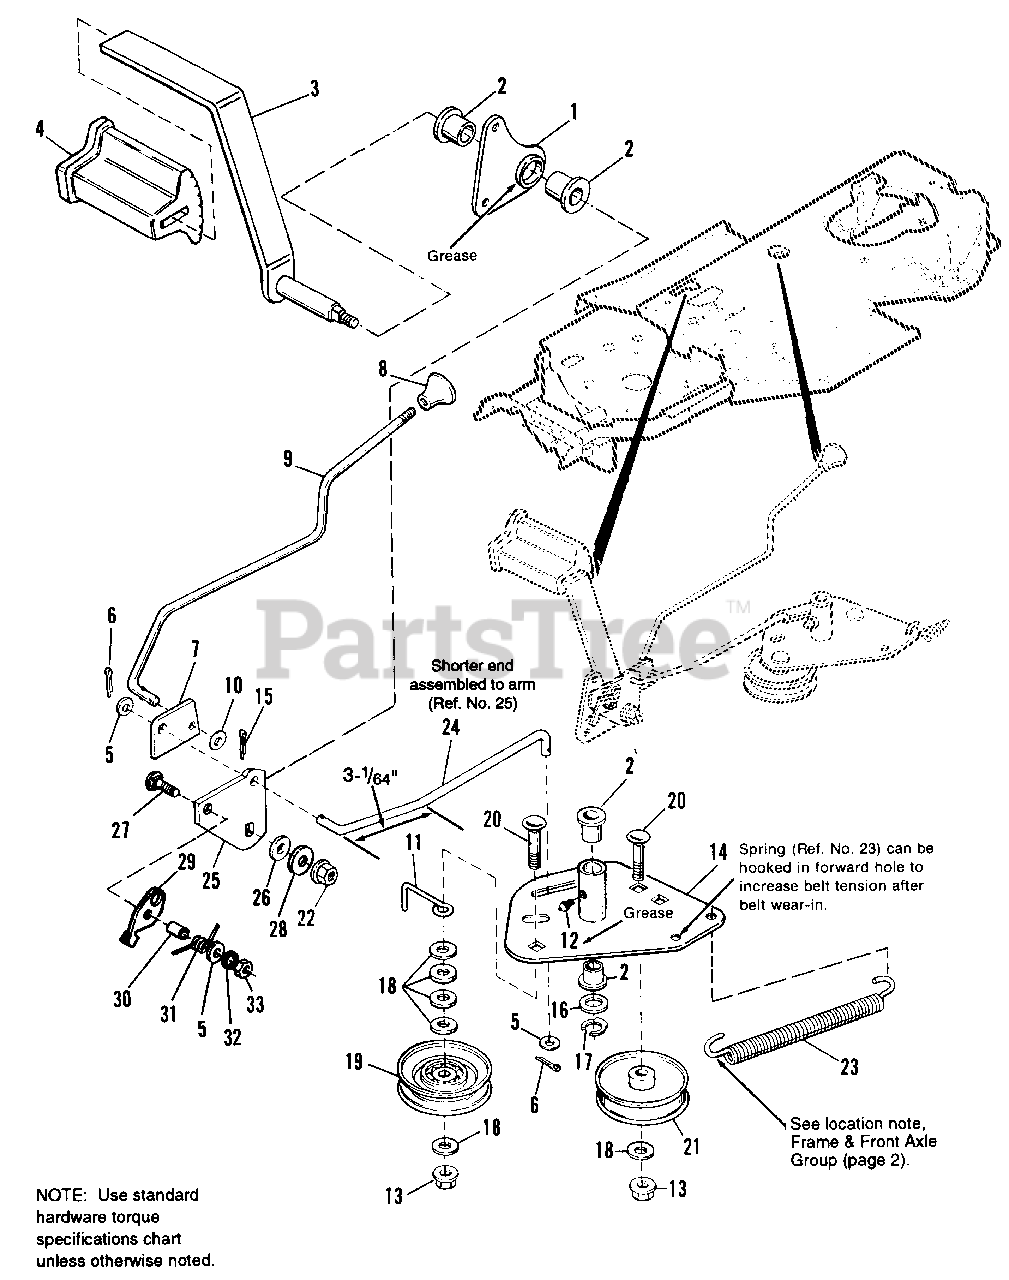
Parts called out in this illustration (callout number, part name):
2	BUSHING, Plastic
3	BRAKE PEDAL ASSY.
4	PAD, Foot Pedal
5	WASHER, Plain, 11/32
6	COTTER PIN
7	CAM, Parking Brake
8	KNOB, Plastic
9	ROD, Parking Brake
10	WASHER, Plain, 9/32
12	FITTING, Grease
13	NUT, Flange, Whizlock, 3/8-16
14	ARM ASSY., Idler
15	COTTER PIN
16	WASHER, 5/8
17	KLIPRING, 5/8
18	WASHER, Plain, 13/32
20	CARRIAGE BOLT, 3/8-16 x 1-3/4
21	PULLEY, Idler
22	NUT, Hex Esna, 3/8-16
23	SPRING, Drive
24	ROD, Clutch, 5/16 Dia.
25	ARM, Foot Pedal
26	WASHER
27	CARRIAGE BOLT, 5/16-18 x 1-1/4
28	WASHER, Plain, 3/8
29	SWITCH, Adaptor
31	SPRING, Torsion
32	LOCKWASHER, 5/16
33	NUT, Hex, 5/16-18
